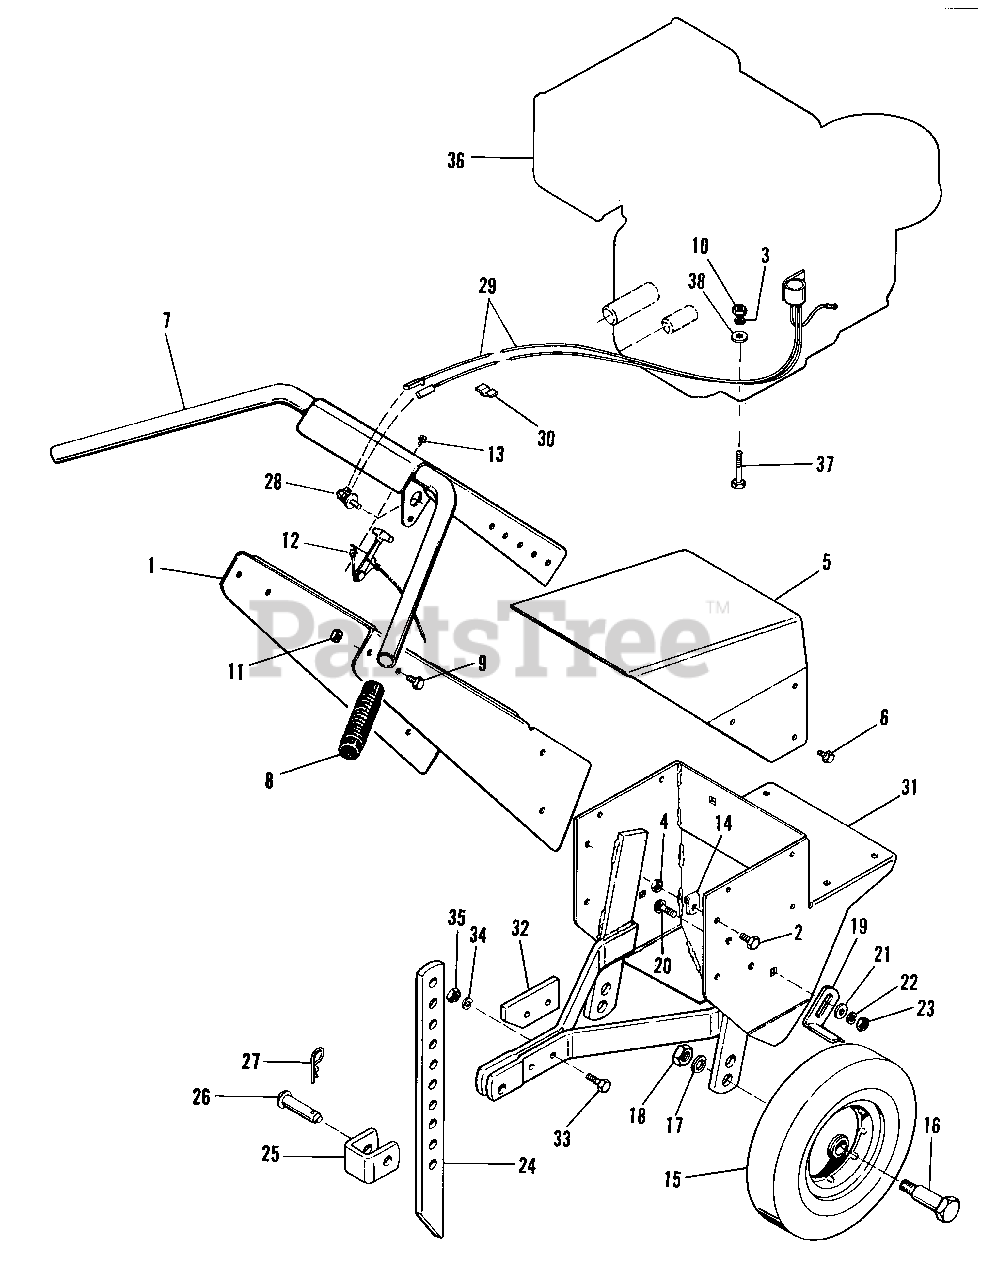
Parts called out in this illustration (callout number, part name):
1	CHANNEL ASSY
2	SCREW, Hex, Flange, 3/8-16 x 1
3	LOCKWASHER, 5/16
4	LOCKNUT, Flange, 3/8-16
6	SCREW, Taptite, 1/4-20 x 3/8
7	HANDLE BAR ASSY
9	SCREW, Hex, Flange, 5/16-18 x 3/4
10	NUT, Hex, Full, 5/16-18
11	LOCKNUT, Flange, 5/16-18
12	CONTROL ASSY, Throttle
13	SCREW, Self-Tapping, 1/4-20 x 1/2
15	WHEEL & TIRE ASSY
16	BOLT, Shoulder
17	LOCKWASHER, 1/2
18	NUT, Hex, Full, 1/2-13
20	BOLT, Carriage, 3/8-16 x 1
21	WASHER, Plain, 5/16
22	LOCKWASHER, 3/8-16
23	NUT, Hex, 3/8-16
24	BAR, Depth
27	CLIP, Spring
29	IGNITION INTERLOCK
30	CLIP, Wire
31	FRAME ASSY
32	PLATE, Stop
33	CAPSCREW, Hex, 3/8-16 x 1
34	LOCKWASHER, 3/8
35	NUT, Hex, Full, 3/8-16
37	CAPSCREW, Hex, 5/16-18 x 1-3/4
38	WASHER, Plain, 5/16
